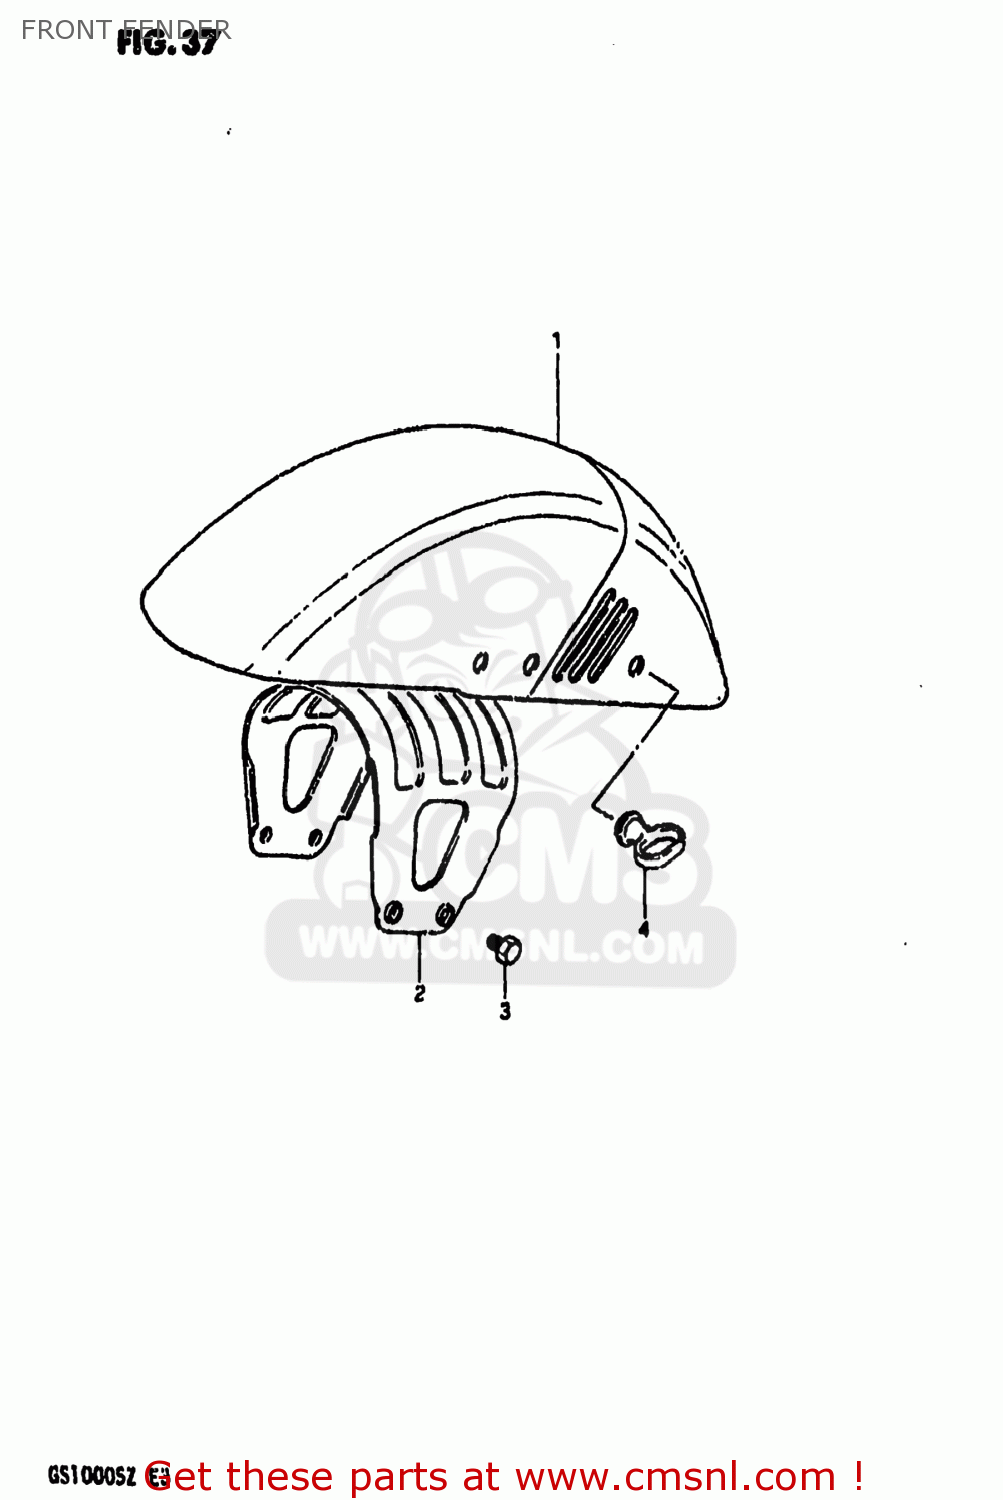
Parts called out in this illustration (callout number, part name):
1	FR FENDER
2	BRACE,FRONT FENDER
3	BOLT 8X16
4	GUIDE,CABLE
